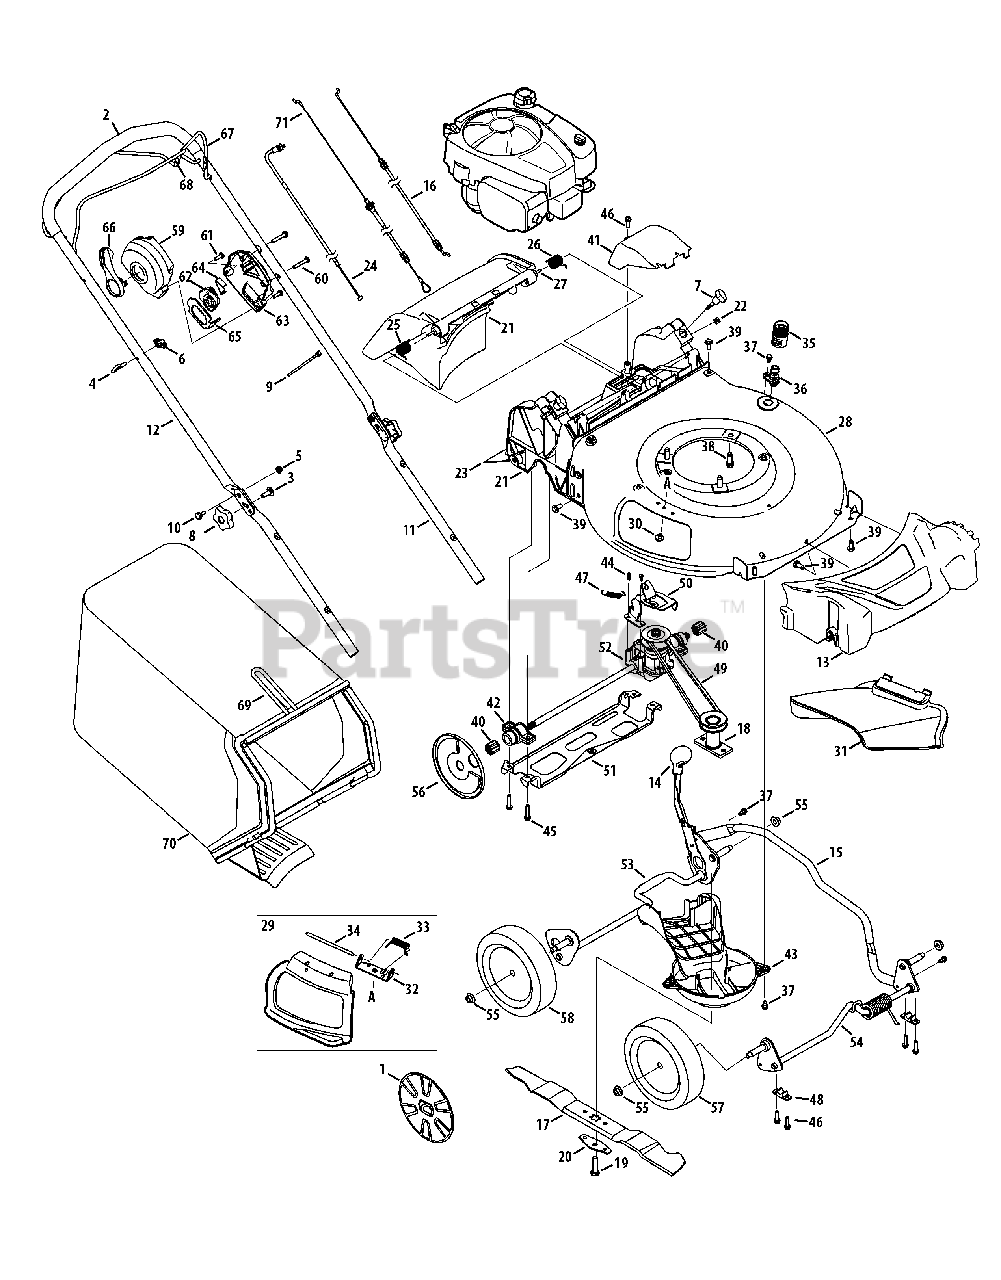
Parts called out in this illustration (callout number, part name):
1	Hubcap
2	Foam Grip
3	Carriage Screw ,5/16-18
4	Rope Guide
5	Nut, Flange Lock, 1/4-20
7	Wing Nut
8	Star Knob
9	Cable Tie
10	Shoulder Screw, .375 x .126 x 1/4-20
11	Lower Handle
12	Upper Handle
13	Front Cover
14	Adjustment Knob
16	Control Cable
17	Mulching Blade
18	Blade Adapter
19	Screw, 3/8-24 x 1.50
20	Blade Bell Support
21	Rear Discharge Door Assembly
22	Nut, Sq., 1/4-20
23	Trail Shield
24	Speed Select Cable
25	Torsion Spring - RH
26	Torsion Spring - LH
27	Pivot Rod
28	21" Deck
29	Mulch Plug (Incl. 32-34)
31	Side Discharge Chute
32	Chute Deflector Bracket
33	Torsion Spring
34	Hinge Pin
35	Water Nozzle Adapter
36	Water Nozzle
37	Scr., Shldr., 1/4-20 x .50
38	Screw, tt, 3/8-16 x 1.00
39	Screw, 5/16-14 x .750
40	Spur Gear, 10T
41	Transmission Cover
42	Bearing Assembly
43	Engine Baffle
44	Screw, Hex Washer, .159 x .43
45	Screw, 1/4-15 x 1.25
46	Screw, 1/4-15 x .750
47	Exten. Spring, 2.675
48	Bush., Block
49	V-Belt
50	Transmission Bracket
51	Rear Support Bracket
52	Transmission
53	Rear Hgt. Adjust./Axle Assembly
54	Front Axle Assembly
55	Flange Lock Nut, 3/8-16
56	Wheel Dust Cover
57	Front Wheel, 8 x2
58	Rear Wheel, 8 x 2
59	Control Housing Assembly
60	Screw, 1/4-15 x 1.50
61	Screw, 1/4-15 x .750
62	Speed Cable Actuater
63	Lower Control Housing
64	Shift Lever Spring
65	Cable Adjustment Plate
66	Speed Select Lever
67	Blade Control
68	Drive Control
69	Grass Catcher Frame
70	Grass Bag
71	Speed Adjustment Cable
